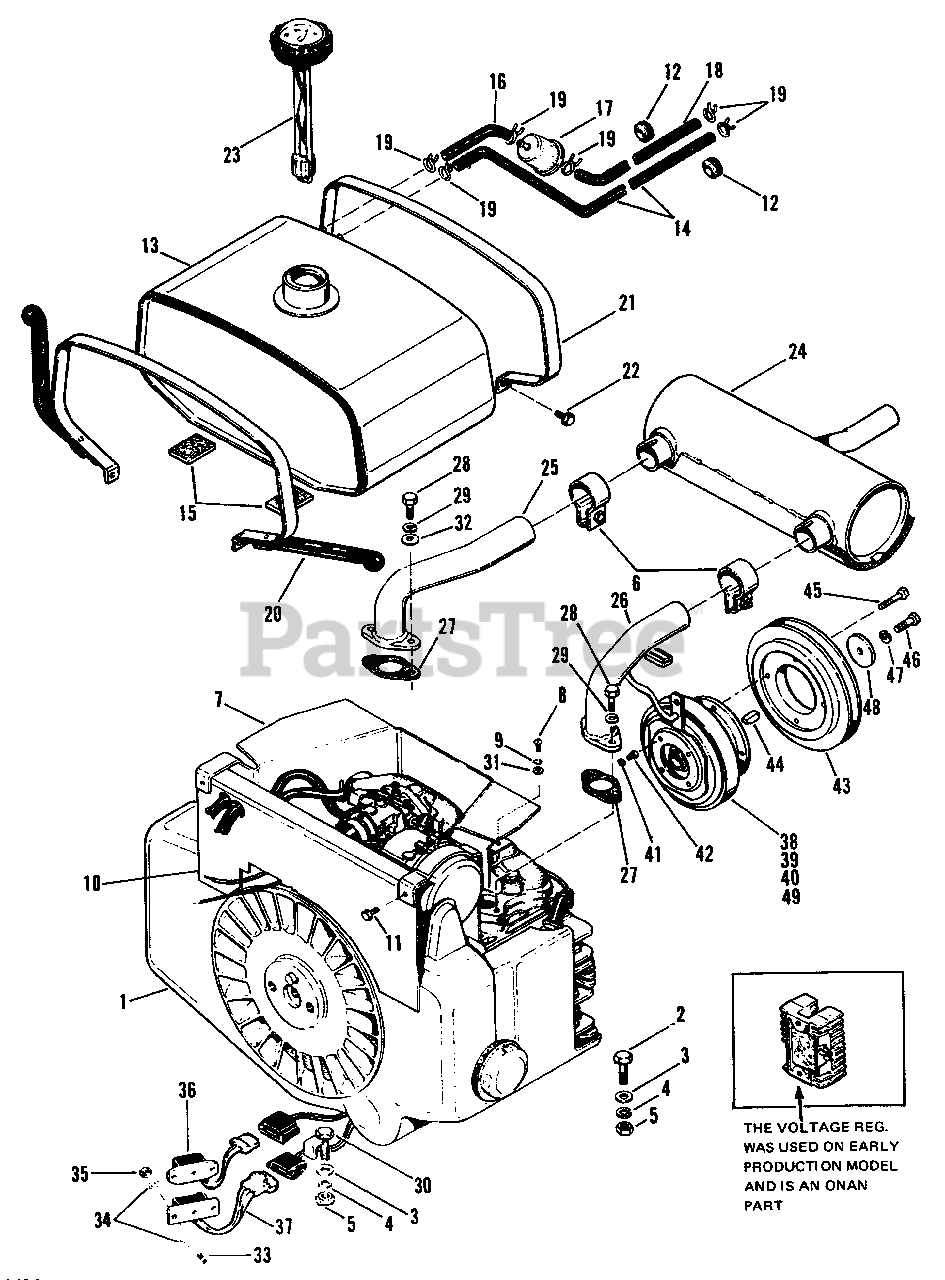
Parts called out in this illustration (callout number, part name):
2	Hex Capscrew, 7/16"-14 x 1-1/2" lg.
3	Plain Washer, 7/16"
4	Lockwasher, 7/16"
5	Full Hex Nut, 7/16"-14
6	Clamp
7	Heat Shield Assembly
8	Round Head Screw, No. 10-32 x 3/8" lg.
9	Lockwasher, No. 10
10	Front Shroud
11	Self-Tapping Screw, 1/4"-20 x 1/2" lg.
13	Fuel Tank Assembly
14	Fuel Line, Return
15	Felt Gasket
16	Fuel Line
17	Fuel Filter
18	Fuel Line
20	Tank Strap Assy., Rear
21	Tank Strap, Front
22	Thread Forming Screw, 1/4-20 x 1" lg.
23	Fuel Gauge (Cap)
25	Exhaust Pipe Assy., L.H.
26	Exhaust Pipe Assy., R.H.
28	Hex Capscrew, 5/16"-18 x 1-1/4" lg.
29	Lockwasher, 5/16"
30	Capscrew Assembly
31	Plain Washer, No. 10
32	Plain Washer, 5/16"
33	Truss Hd. Phillips Screw, No. 10-32 x 1/2" lg.
34	Lockwasher, Shakeproof No. 10
35	Hex Nut, No. 10-32
36	Regulator
37	Rectifier
38	Electric Clutch
39	Field Assembly (For Service Only)
40	Armature Assembly (For Service Only)
41	Lockwasher, No. 10
42	Socket Head Screw, No.10-32 x 1/2" lg.
45	Self-Tapping Screw, 5/16"-18 x 1-1/2" lg.
46	Hex Capscrew, 3/8"-21 x 1" lg.
47	Lockwasher, 3/8"
49	Bearing (For Service Only)
